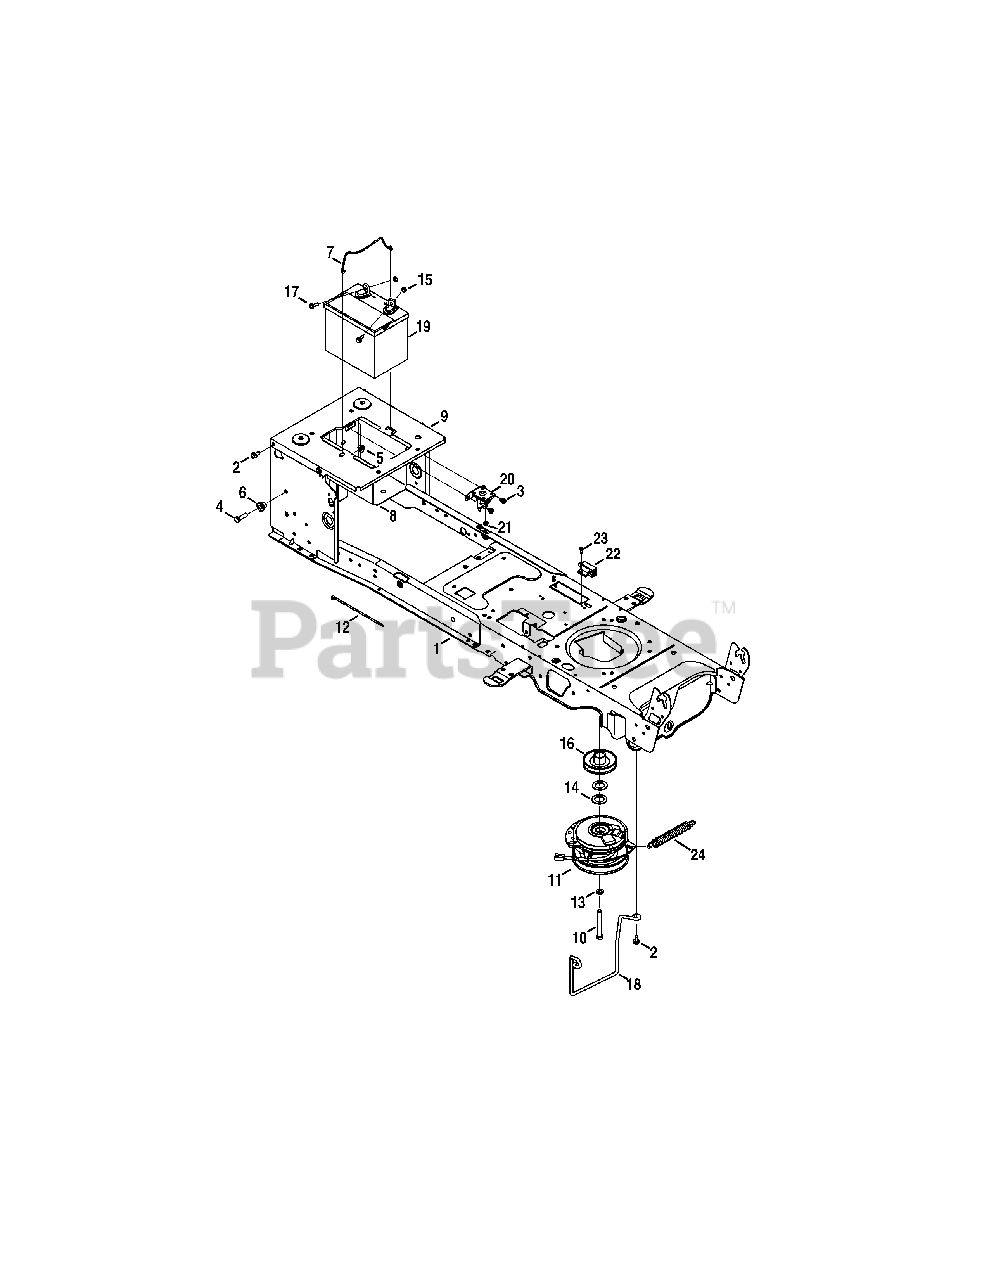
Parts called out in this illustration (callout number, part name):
1	Frame
2	Taptite Screw, Indented Washer, 5/16-18:.750
3	Taptite Screw, Indented Washer, 1/4-20:0.375
4	Hex Head Screw, 3/8-16:1.25
5	Flangelock Nut, 3/8-16
6	Shoulder Spacer, .38 X 1.0 X .70
7	Battery Holder Rod
8	Battery Tray
9	Seat Frame Bracket
10	Hex Head Screw, 7/16-20:3.50
11	Electric PTO Clutch
12	Cable Tie, 3/16 x .05 x 7.4
13	Lock Washer, 7/16
14	Flat Washer, 1.031 x 1.620 x .095
15	Sems Nut, 1/4-20
16	Electric PTO Engine Pulley
17	Hex Head Flange, 1/4-20:.75
18	Belt Guard
19	Battery, DIEHARD 725-05088
20	Solenoid, 12 V
21	Flangelock Nut, 1/4-20
22	Interlock Switch
23	Shoulder Screw, #10-32:.500
24	Extension Spring, .56 Od. x 5.52 Lg.
